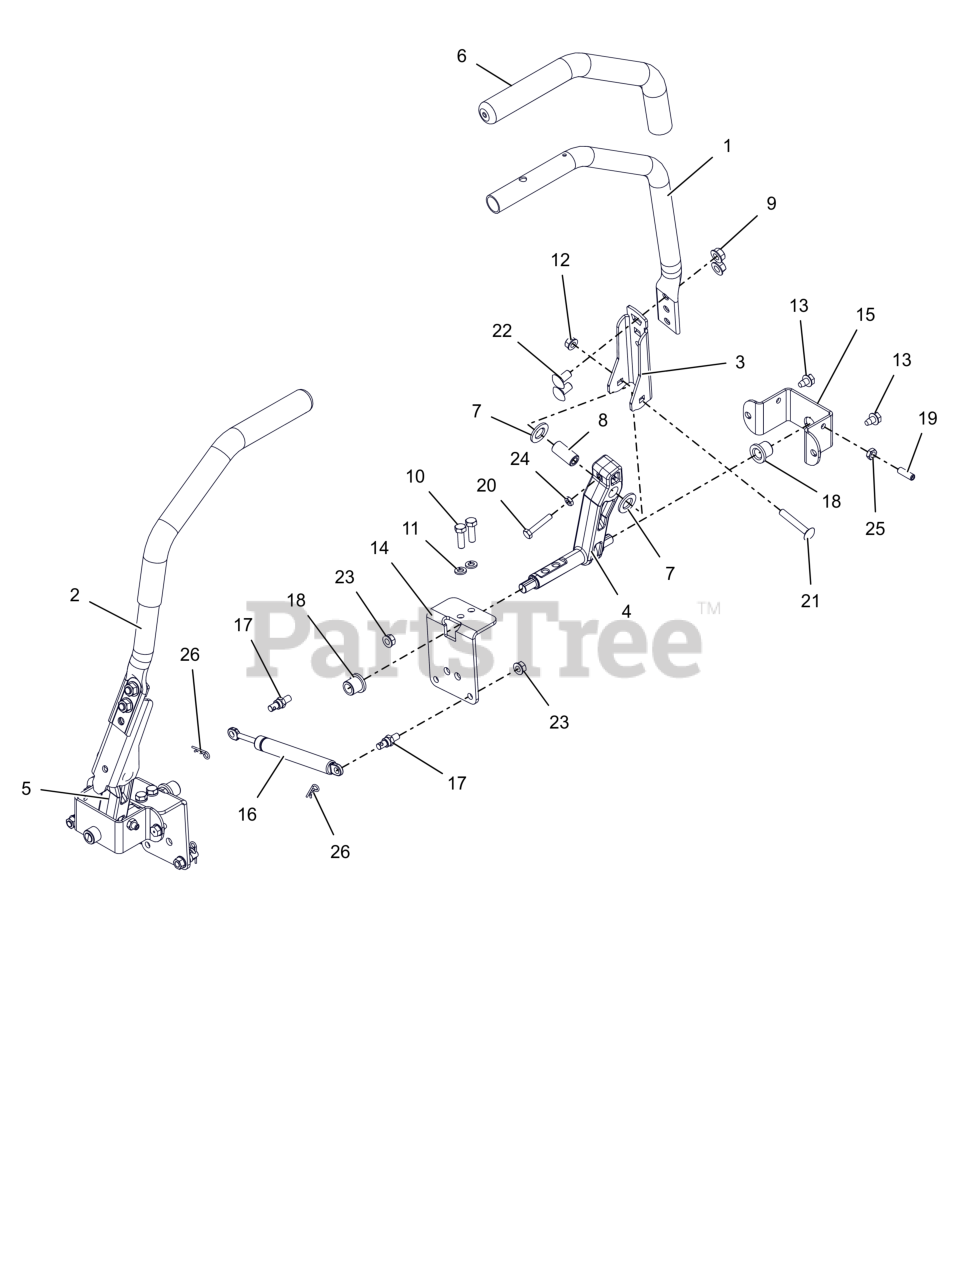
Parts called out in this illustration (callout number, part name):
1	HANDLE, STEERING - LH (BLACK)
2	HANDLE, STEERING - RH (BLACK)
3	ARM, CONTROL -UPPER RH (BLACK)
4	STEERING, LH LWR CAST ARM
5	STEERING, RH LWR CAST ARM
6	GRIP, HANDLEBAR 15" FOAM
7	WSHR, FRICTION
8	BSHG-SLV .342 X .627 X 1.331
9	NUT-LK-CTR-FLG .375-16 GF ZCC
10	BLT, HEX .31-18X1.00 G8 ZCC
11	WSHR,LK-REG .312X.078 ZCC
12	NUT,LK-CTR-FLG .31-18 GF ZCC
13	SCR,TAP .312-18X.50 HWH TR ZCC
14	BRKT, STEEERING
15	BRKT, STEERING
16	DAMPER, STRAIGHT MOUNT
17	COUPLER, DAMPER MOUNT
18	BHSG-FLG .500X.750X.750X.125
19	SCR-SET, .312-18X1.000
20	BLT, HEX 0.25-20X1.5F GR5 ZCC
21	BLT, RHSSN .31-18X2.00 G5 ZCC
22	BTL,RHSSN .375-16 X 0.75 G5 FPB
23	NUT-LK-TOP-FLG .312-18 GF ZCC
24	NUT-JAM .250-20 G2 ZCC
25	NUT-JAM .312-18 G2 ZCC
26	PIN, HAIR #213 .08X1.19 ZCC
